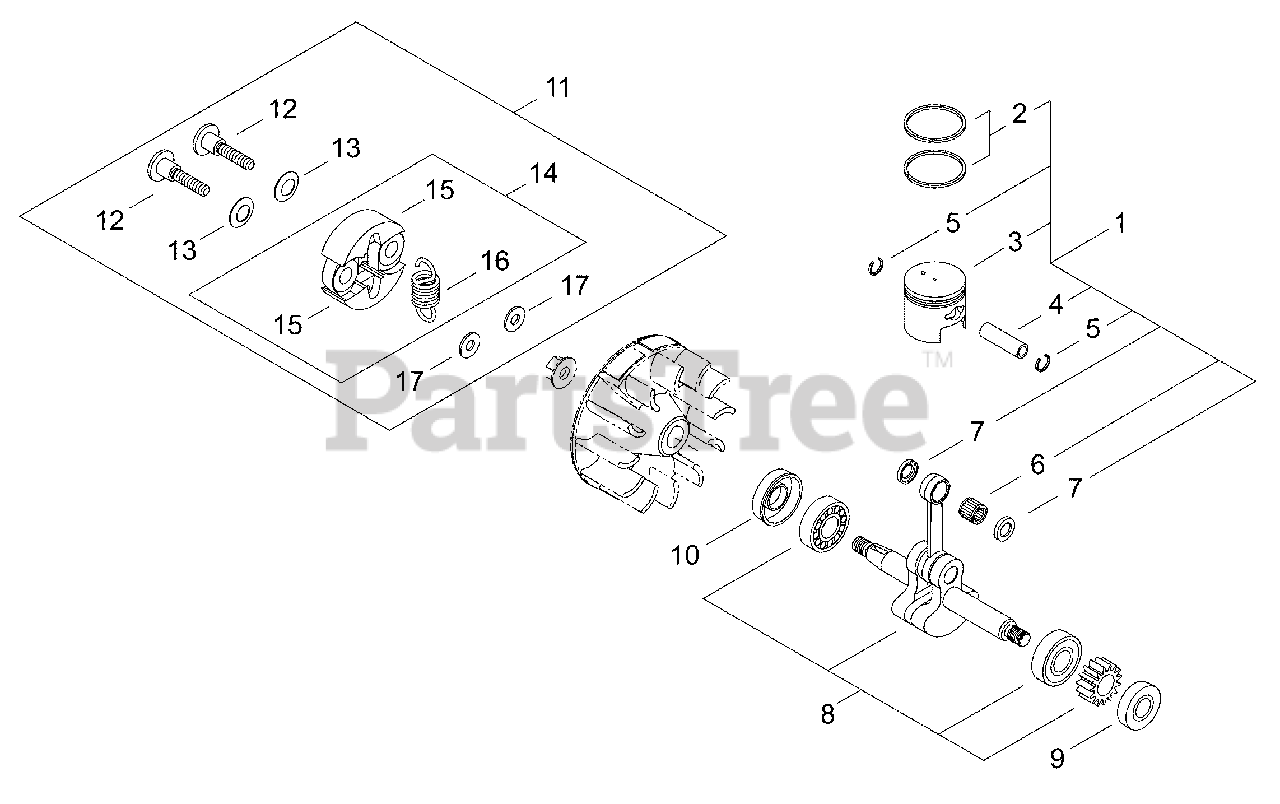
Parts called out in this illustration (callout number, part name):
1	PISTON KIT
2	RING, PISTON
3	PISTON
4	PIN, PISTON
5	RING, RETAINING
6	BEARING, NEEDLE
7	WASHER, THRUST - 10
8	CRANKSHAFT ASSY
9	SEAL, OIL - 12
10	SEAL, OIL
11	CLUTCH SHOE ASSY
12	BOLT, CLUTCH
13	WASHER - SPRING
14	CLUTCH SHOE ASSY
15	SHOE, CLUTCH
16	SPRING, CLUTCH
17	WASHER - 6
